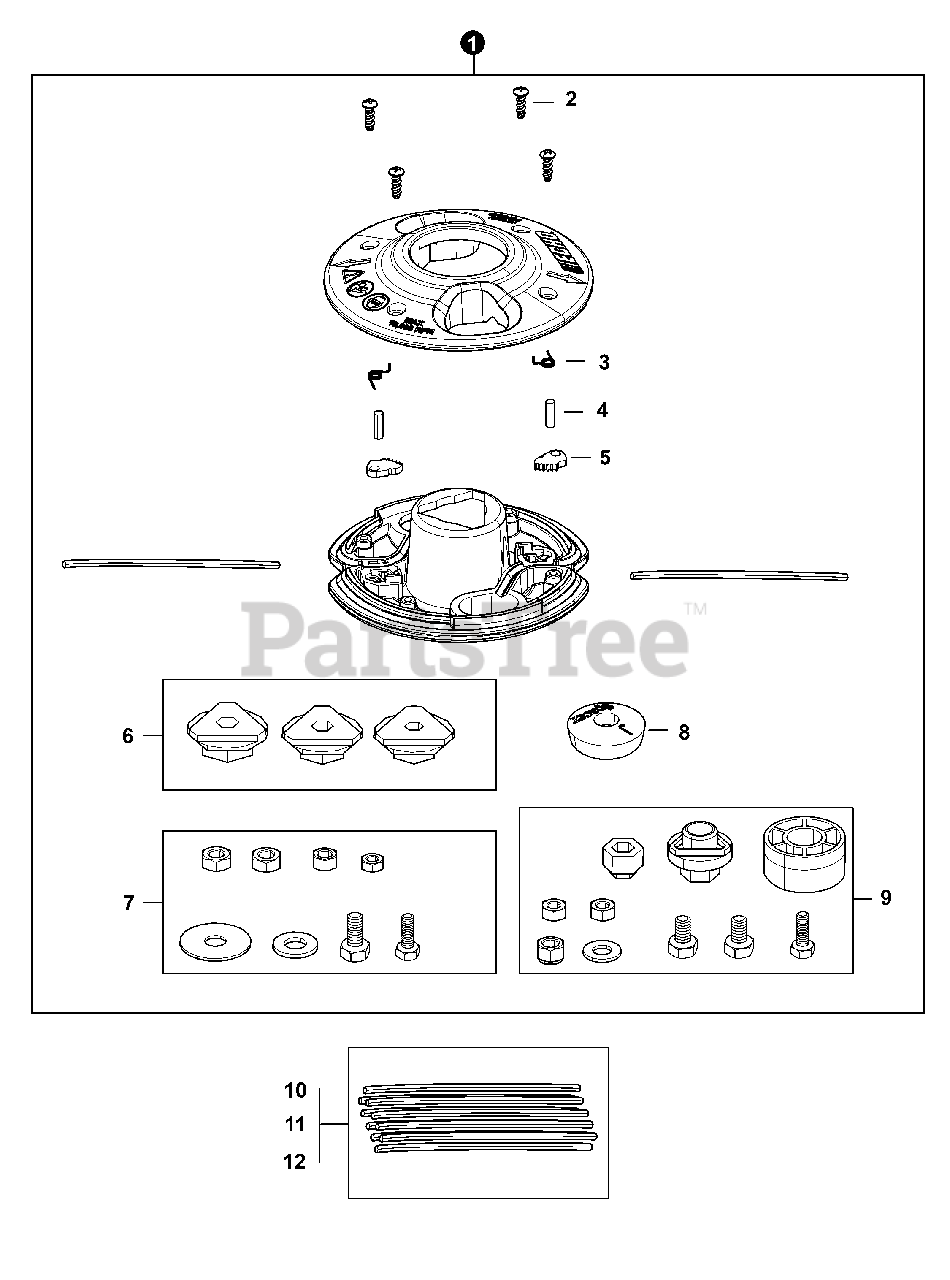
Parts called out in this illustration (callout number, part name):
1	TRIMMER HEAD, RAPID-LOADERT- 2 LINE
2	SCREW, TAPPING #8×0.5
3	SPRING, TORSION
6	ADAPTOR KIT
7	HARDWARE PACK
9	HARDWARE PACK
10	LINE, TRIMMER - 0.095 DIA. (PKG. OF 10)
11	LINE, TRIMMER - 0.095 DIA. (PKG. OF 20)
12	LINE, TRIMMER - 0.095 DIA. (PKG. OF 50)
